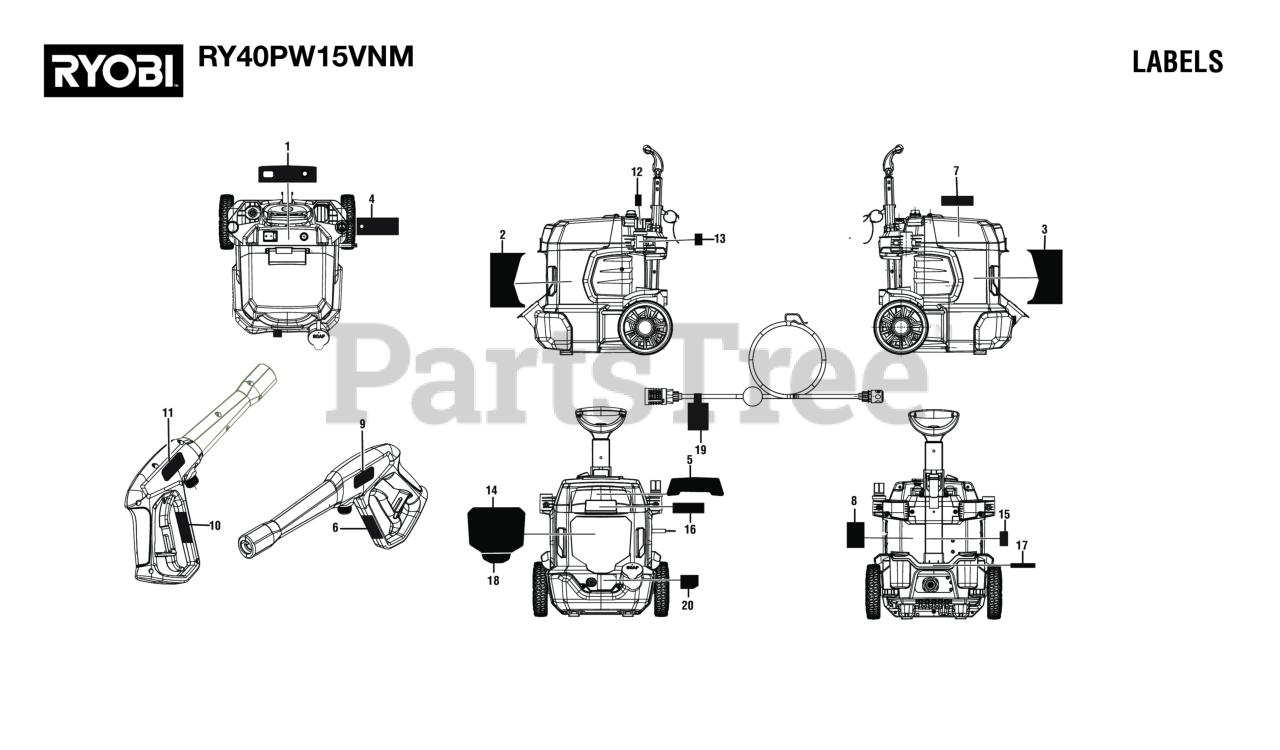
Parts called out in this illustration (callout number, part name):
1	On/Off Label
2	Warning Label (Eng)
3	Warning Label (Fr)
4	Starting Instructions Label
4	Spanish Hangtag
4	Nozzle Hangtag (PS141913)
5	Battery Notice Label
6	Trigger Handle Data Label
7	Inquires Label (Ryobi)
8	Data Label
9	Trigger Handle Warning Label (English)
10	Trigger Handle Warning Label (French/Spanish)
11	Trigger Handle Label (Logo Label)
12	Adaptor Label
13	Adaptor Location Label
14	Performance Label
15	QR Code Label
16	Ryobi Logo Label
17	Self-Priming ACC Instruction Label
18	Self-Priming Notice Label
19	Siphon Hose Wrap Label
20	Soap Dilution Label
